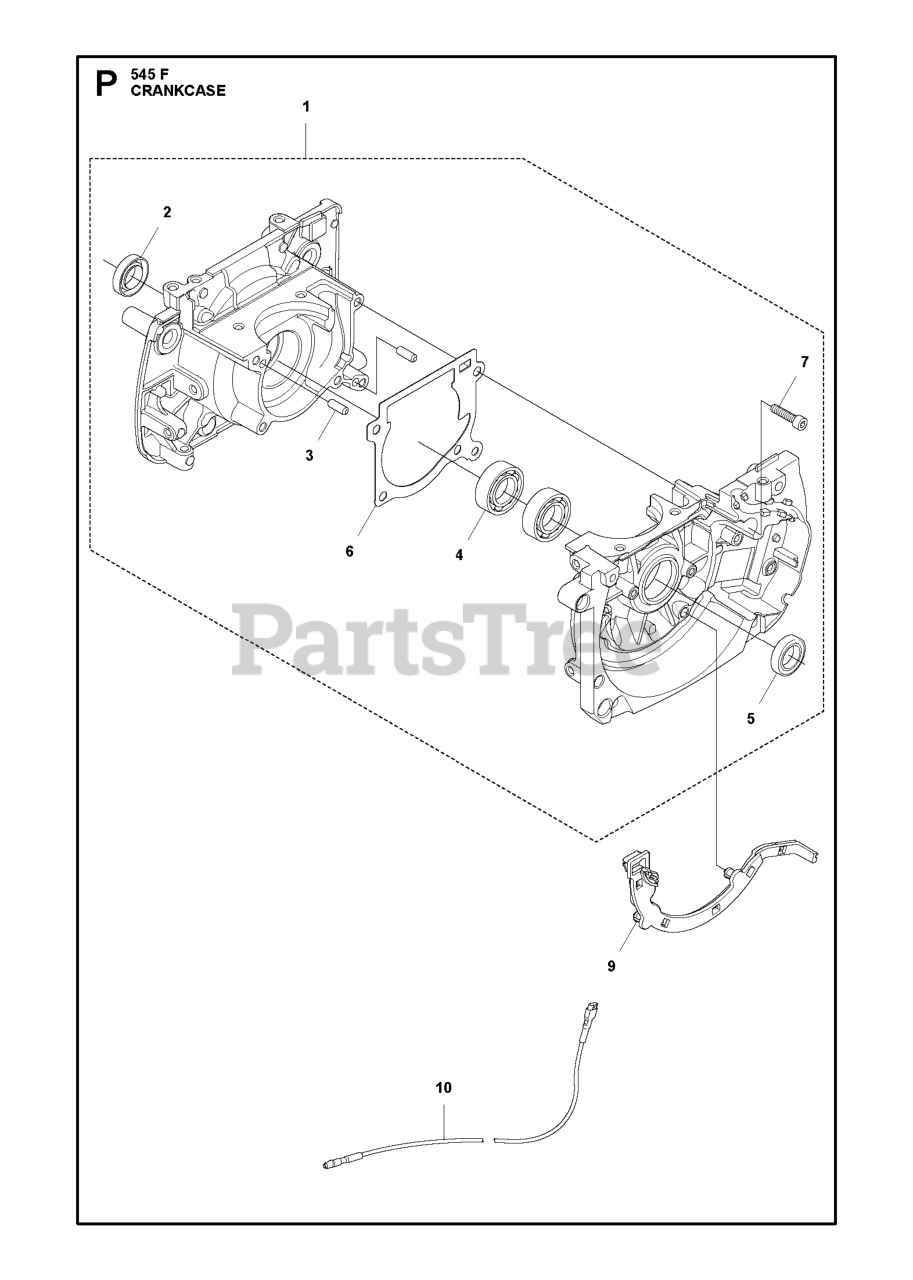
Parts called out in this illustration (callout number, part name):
1	CRANKCASE ASSY SPARE PART KIT
2	RADIAL SEAL
3	GUIDE BUSHING
4	BALL BEARING
9	CABLE HOLDER
10	SHORT CIRCUIT CABLE
